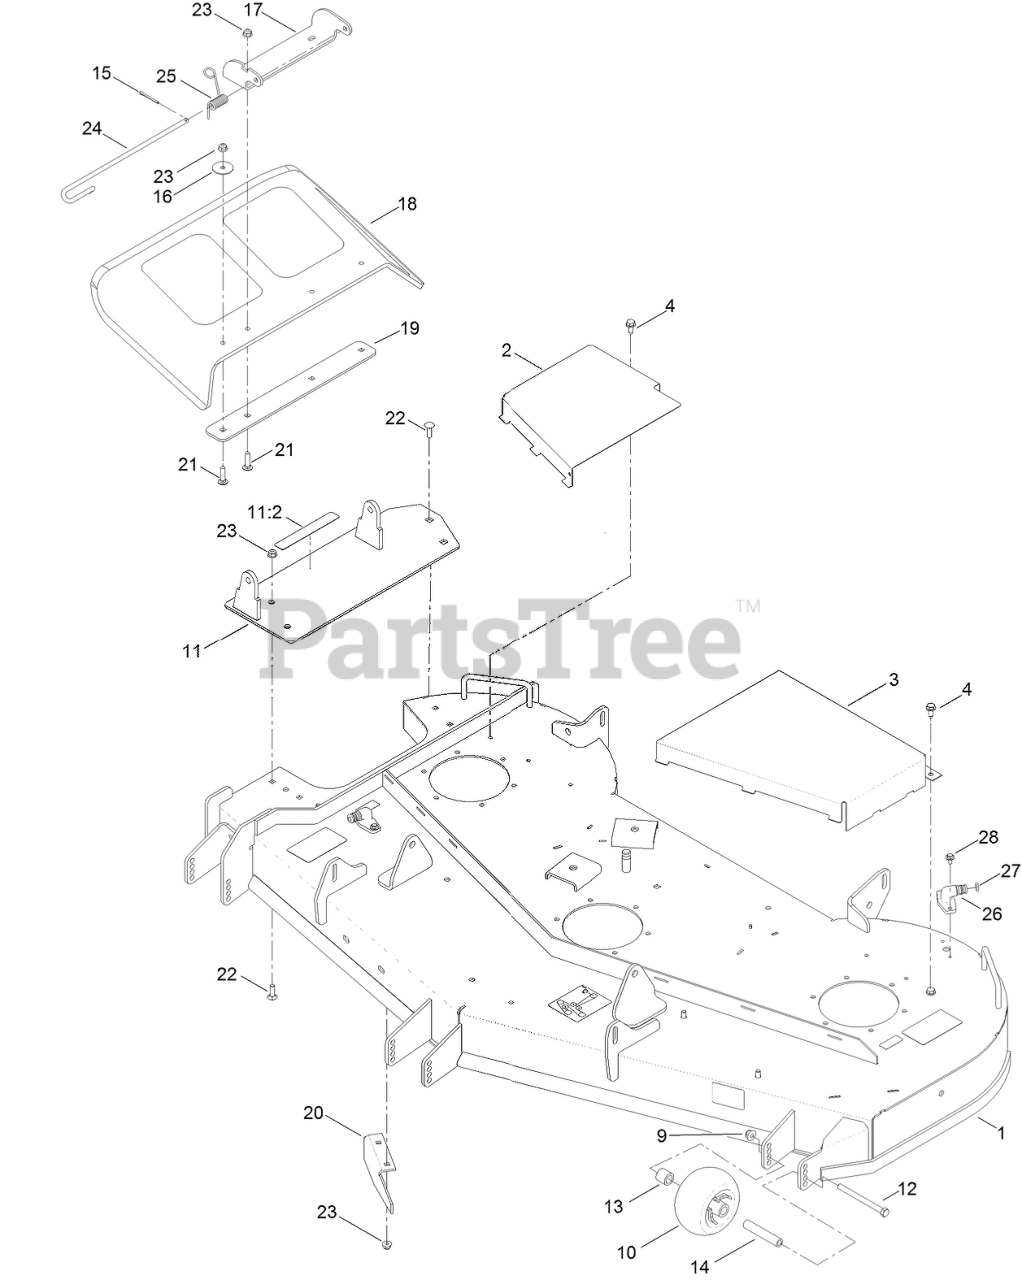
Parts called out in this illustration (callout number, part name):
1	54 INCH DECK ASM
2	COVER-BELT, RH
3	COVER-BELT, LH
4	SCREW-HWHTF
9	NUT-HF, NI
10	ROLLER-SCALP, ANTI
11	PIVOT-DEFLECTOR
11:2	DECAL-DANGER
12	SCREW-HH
13	SPACER-AXLE, REAR
14	TUBE-SPANNER
15	PIN-COTTER
16	WASHER-FLAT
17	BRACKET-DEFLECTOR, UPPER
18	DEFLECTOR
19	PLATE-DEFLECTOR
20	BAFFLE-CUTOFF
21	SCREW-CARR
22	SCREW-CARR
23	NUT-HF, NI
24	PIN-CHUTE
25	SPRING-TORSION
26	FITTING-WASHOUT
27	O-RING
28	SCREW-HHFTF
